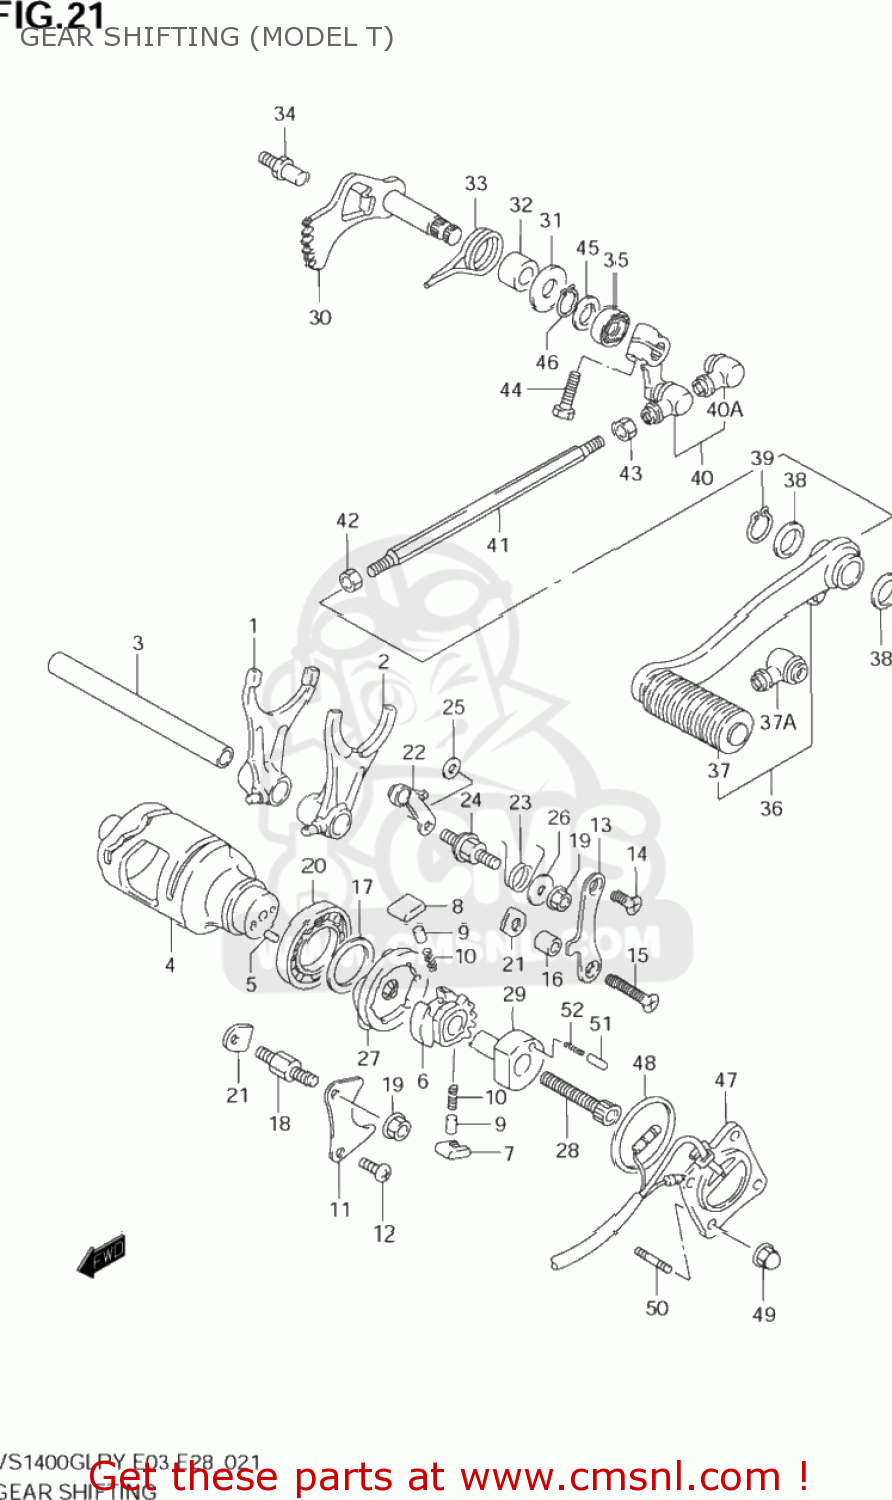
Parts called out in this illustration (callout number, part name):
1	FORK,GEAR SHIFT NO.1
2	FORK,GEAR SHIFT NO.2
3	SHAFT,GEAR SHIFT FORK(L:152)
4	CAM,GEAR SHIFT
5	PIN
6	GEAR,GEARSHIFT CAM DRIVE
7	PAWL,GEAR SHIFT NO.1
8	PAWL,GEAR SHIFT NO.2
9	PIN(5X8)
10	SPRING
11	LIFTER,GEAR SHIFT POLE
12	SCREW
13	GUIDE,GEAR SHIFT CAM
14	SCREW
15	SCREW
16	SPACER (6.1X10X14)
17	WASHER(25X32X3)
18	BOSS,SHIFT PAWL LIFTER
19	NUT
20	BEARING(25X47X8)
21	RETAINER
22	STOPPER,GEAR SHIFT CAM
23	SPRING
24	SUPPORT,CAM STOPPER ARM
25	WASHER
26	WASHER (6.5X18X2)
27	PLATE,GEAR SHIFT CAM
28	BOLT
29	HOLDER,NEUTRAL SWITCH
30	SHAFT,GEAR SHIFT
31	WASHER (12.5X28X1.2)
32	SPACER(12X20X15.3)
33	SPRING
34	STOPPER,SHIFT ARM
35	OIL SEAL
36	LEVER ASSY,GEAR SHIFT
37	RUBBER,GEAR SHIFT PEDAL
37A	COVER,DUST
38	WASHER (14.2X22X1)
39	CIRCLIP
40	ARM,GEAR SHIFT LINK
40A	COVER,DUST
41	ROD,GEAR SHIFT LINK
42	NUT
43	NUT
44	BOLT
45	WASHER,THRUST
46	CIRCLIP,12 MM
47	BASE ASSY,NEUTRAL SW TERMINAL
48	O RING(D:2.4,ID:35.5)
49	NUT
50	BOLT,STUD
51	PIN
52	SPRING
